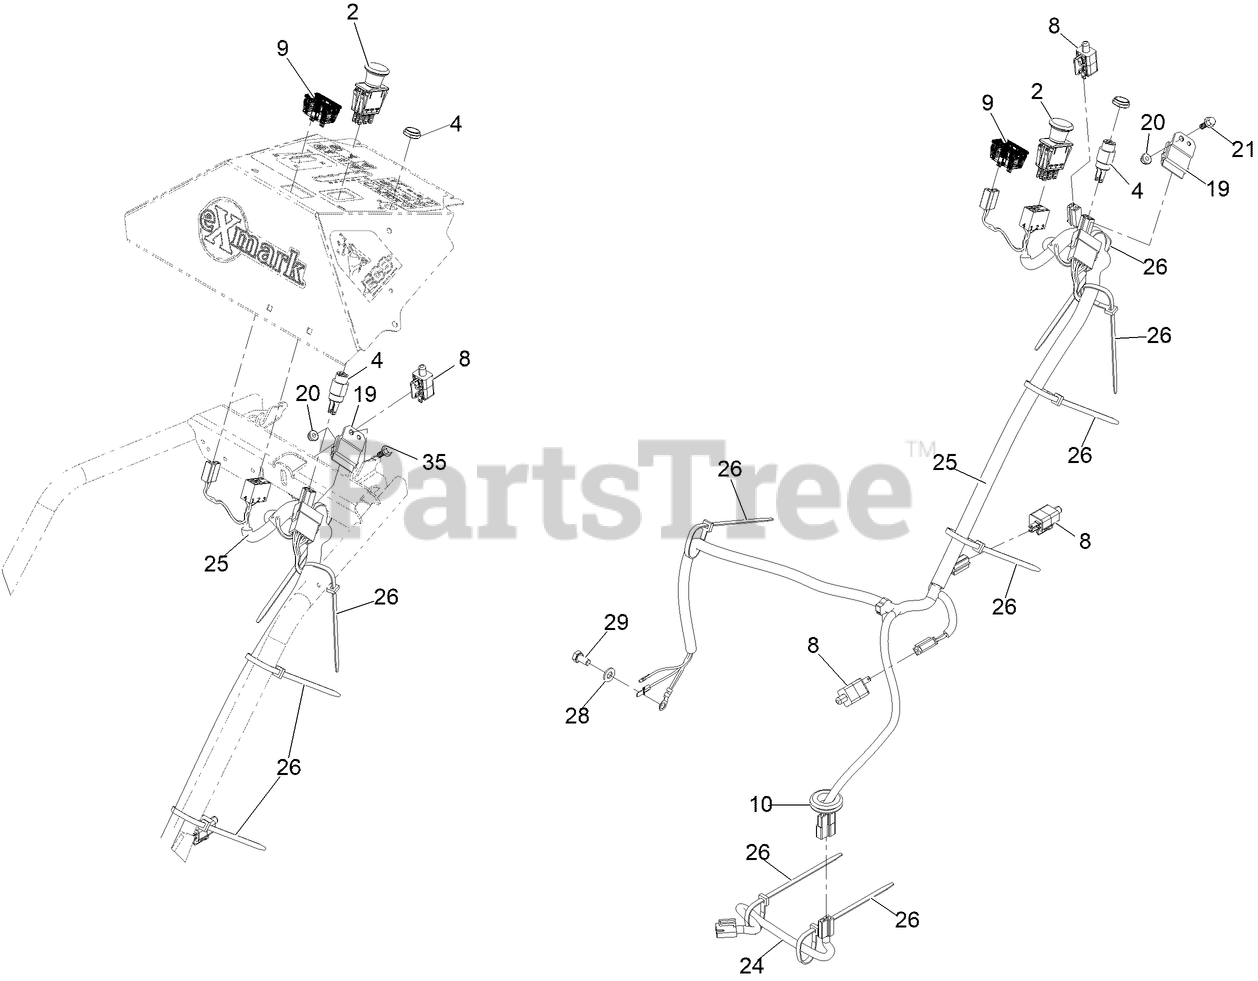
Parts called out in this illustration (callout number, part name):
2	SWITCH-PTO
4	SWITCH & KEY (INCLUDES NU
4	NUT-SWITCH, IGNITION
9	METER-HOUR
10	GROMMET
19	MODULE-INTERLOCK
21	SCREW-HHF
24	HARNESS-CLUTCH PIGTAIL
25	HARNESS-MAIN
26	TIE-CABLE
28	WASHER-PLAIN
29	SCREW-HH
35	SCREW-CARR
